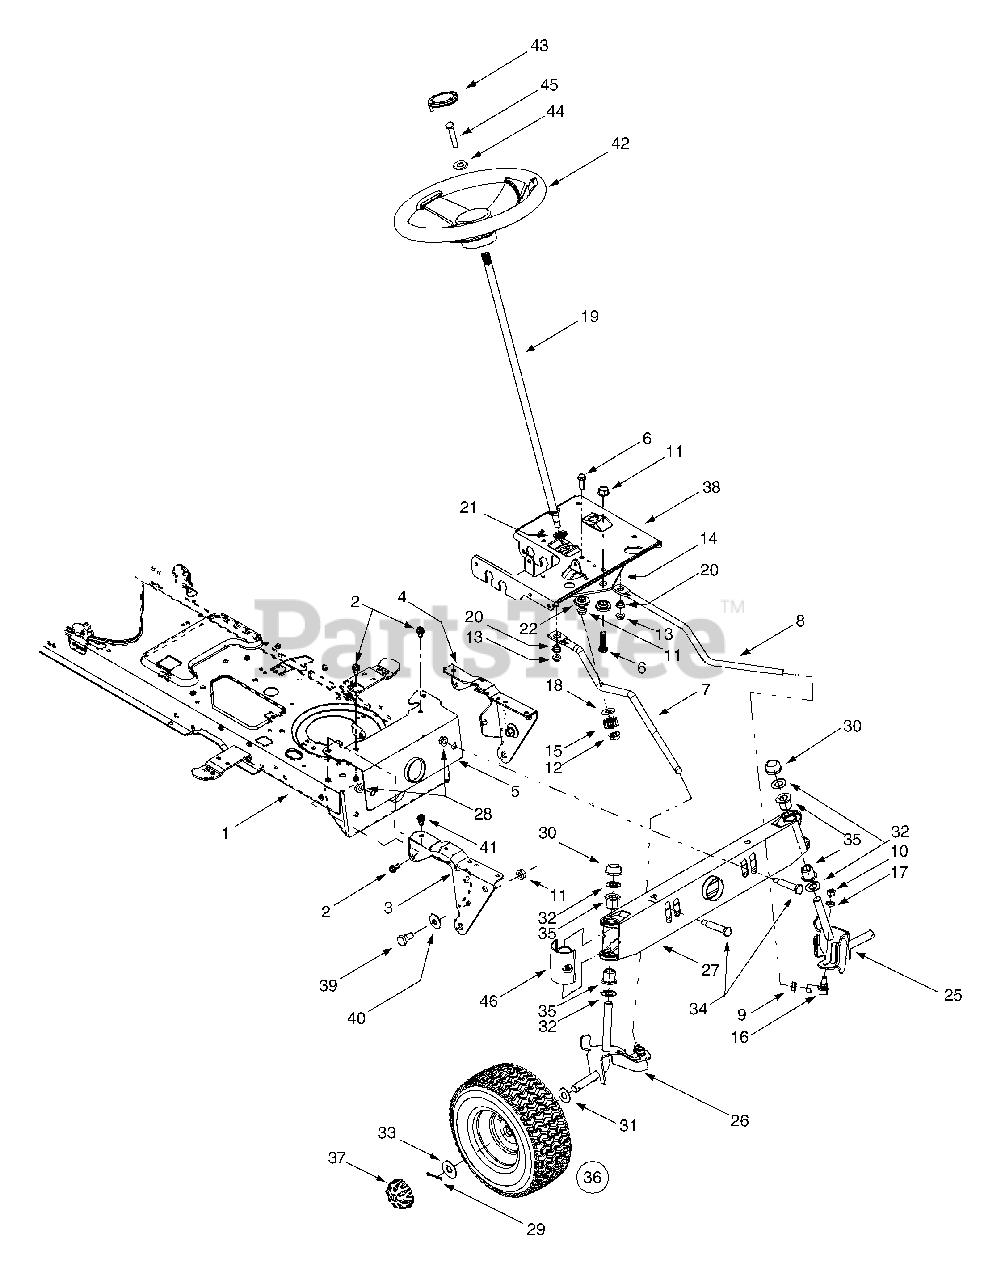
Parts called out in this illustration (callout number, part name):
6	Hex Cap Screw, 3/8-16 x 1.25 (Grade 5)
7	RH Drag Link
9	Jam Nut, 7/16-20 (Grade 2)
10	Hex Nut, 3/8-24 (Grade 2)
11	Flange Lock Nut, 3/8-16
12	Flange Lock Nut, 7/16-20
13	Flange Lock Nut, 5/16-18
14	Steering Gear, 11/90 Ratio
15	Steering Pinion Gear
16	Ball Joint, 7/16-20
17	Lock Washer, 3/8
18	Flat Washer, .51 x 1.12 x .06
19	Steering Shaft, .625 OD x 24.4
20	Plastic Bushing, .38 ID
21	Hex Flange Bearing, 5/8
22	Shoulder Spacer, .38 ID
23	Standard Steering Wheel, 13.25
24	Steering Wheel Cap, Round
25	LH Axle Assembly, .625 Diameter
26	RH Axle Assembly, .625 Diameter
28	Flange Lock Nut, 3/8-16
30	Push Cap, .625
31	Flat Washer, .64 x 1.0 x .12
32	Flat Washer, .64 x 1.24 x .06
33	Flat Washer, .635 x 1.589 x .06
34	Shoulder Screw, .5 x 2.2, 3/8-16
35	Flange Bearing, .632 ID x .937 OD
37	Deluxe Hub Cap (Ref. 33 Required)
39	Shoulder Screw, 3/8-16
40	Bell Washer, .39 x 1.13 x .062
41	Self-tapping Screw, 5/16-18 x .75
42	Steering Wheel, Soft Grip, Three Spoke
43	Steering Wheel Cap, Round
44	Bell Washer, .34 x .872
45	Hex Bolt, 5/16-18 X 1
46	Pivot Bar End Cap w/ Fitting
